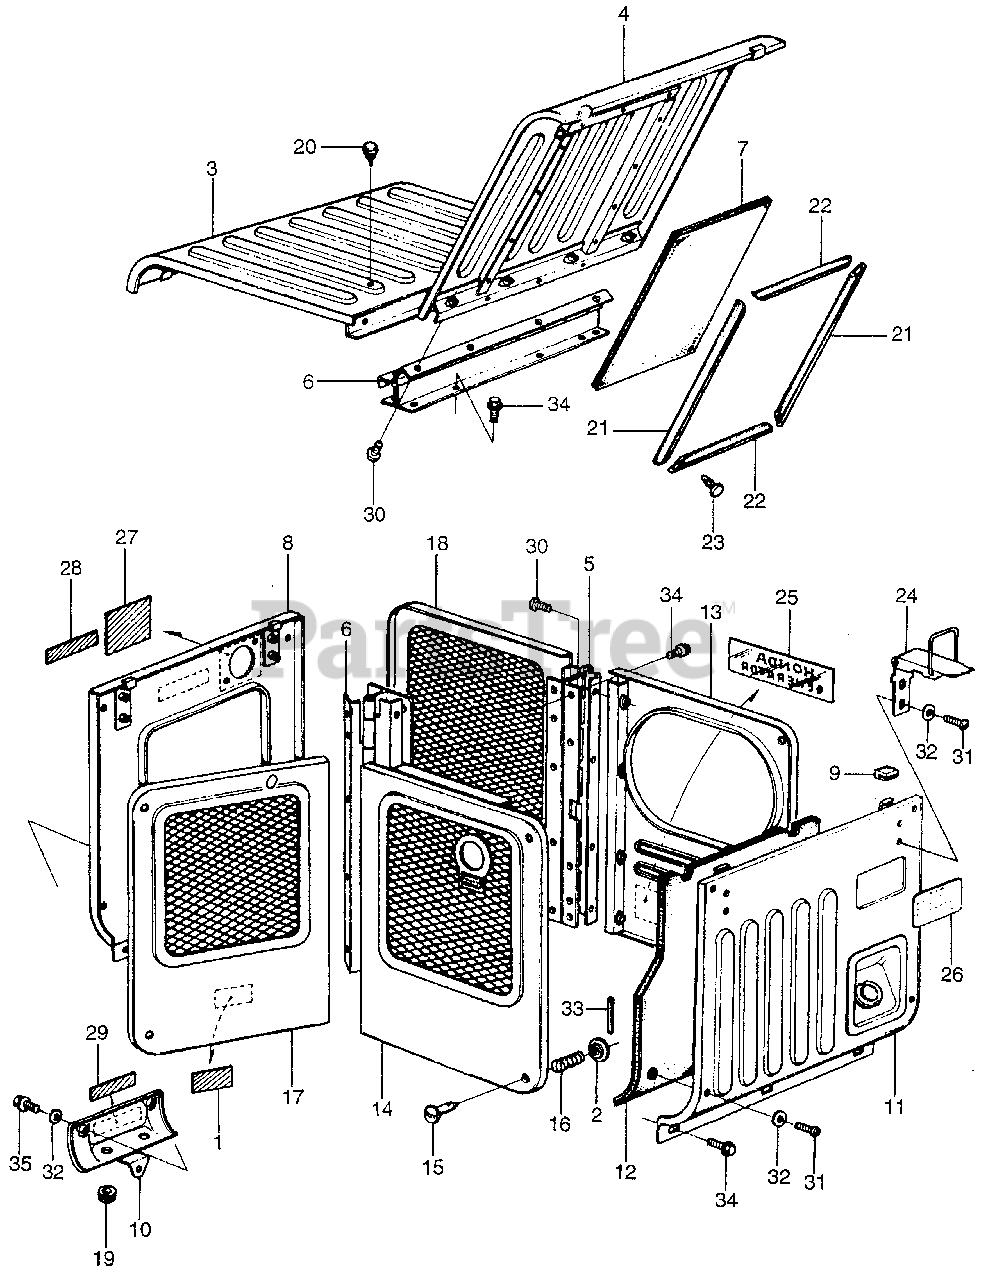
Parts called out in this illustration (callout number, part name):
1	LABEL, BATTERY CAUTION (NOT AVAILABLE)
2	RETAINER, LOCK SPRING
3	COVER, FR. TOP *NH19M* (DARK GRAY METALLIC)
4	COVER, RR. TOP *NH19M* (DARK GRAY METALLIC)
5	HINGE, R. SIDE COVER *NH19M* (DARK GRAY METALLIC)
6	HINGE, COVER TOP *NH19M* (DARK GRAY METALLIC)
7	SHEET, COVER TOP
8	COVER, FR. *NH19M* (DARK GRAY METALLIC)
9	SPACER, COVER
10	COVER, A.C. TERMINAL *NH19M* (DARK GRAY METALLIC)
11	COVER, RR. *NH19M* (DARK GRAY METALLIC)
12	SHEET, RR. COVER
13	COVER, CARBURETOR *NH19M* (DARK GRAY METALLIC)
14	COVER, EX. PIPE *NH19M* (DARK GRAY METALLIC) (NOT AVAILABLE)
15	PIN, COVER LOCK
16	SPRING, COVER LOCK
17	COVER, MUFFLER *NH19M* (DARK GRAY METALLIC)
18	COVER, RADIATOR *NH19M* (DARK GRAY METALLIC)
19	GROMMET, BOOST TUBE
20	RUBBER, SETTING STOPPER (NOT AVAILABLE)
21	RUBBER A, SEAL TOP
22	RUBBER B, SEAL TOP
23	PIN, RUBBER SET
24	LOCK ASSY., COVER TOP (NOT AVAILABLE)
25	EMBLEM (NOT AVAILABLE)
26	MARK B, CAUTION
27	MARK C, CAUTION
28	MARK, CO. CAUTION
29	MARK, A.C. TERMINAL
30	SCREW, PAN (6X8)
31	SCREW, PAN (6X12)
32	WASHER, PLAIN (6MM)
33	PIN, SPRING (3X18)
34	BOLT, FLANGE (6X12)
35	BOLT, FLANGE (6X16)
